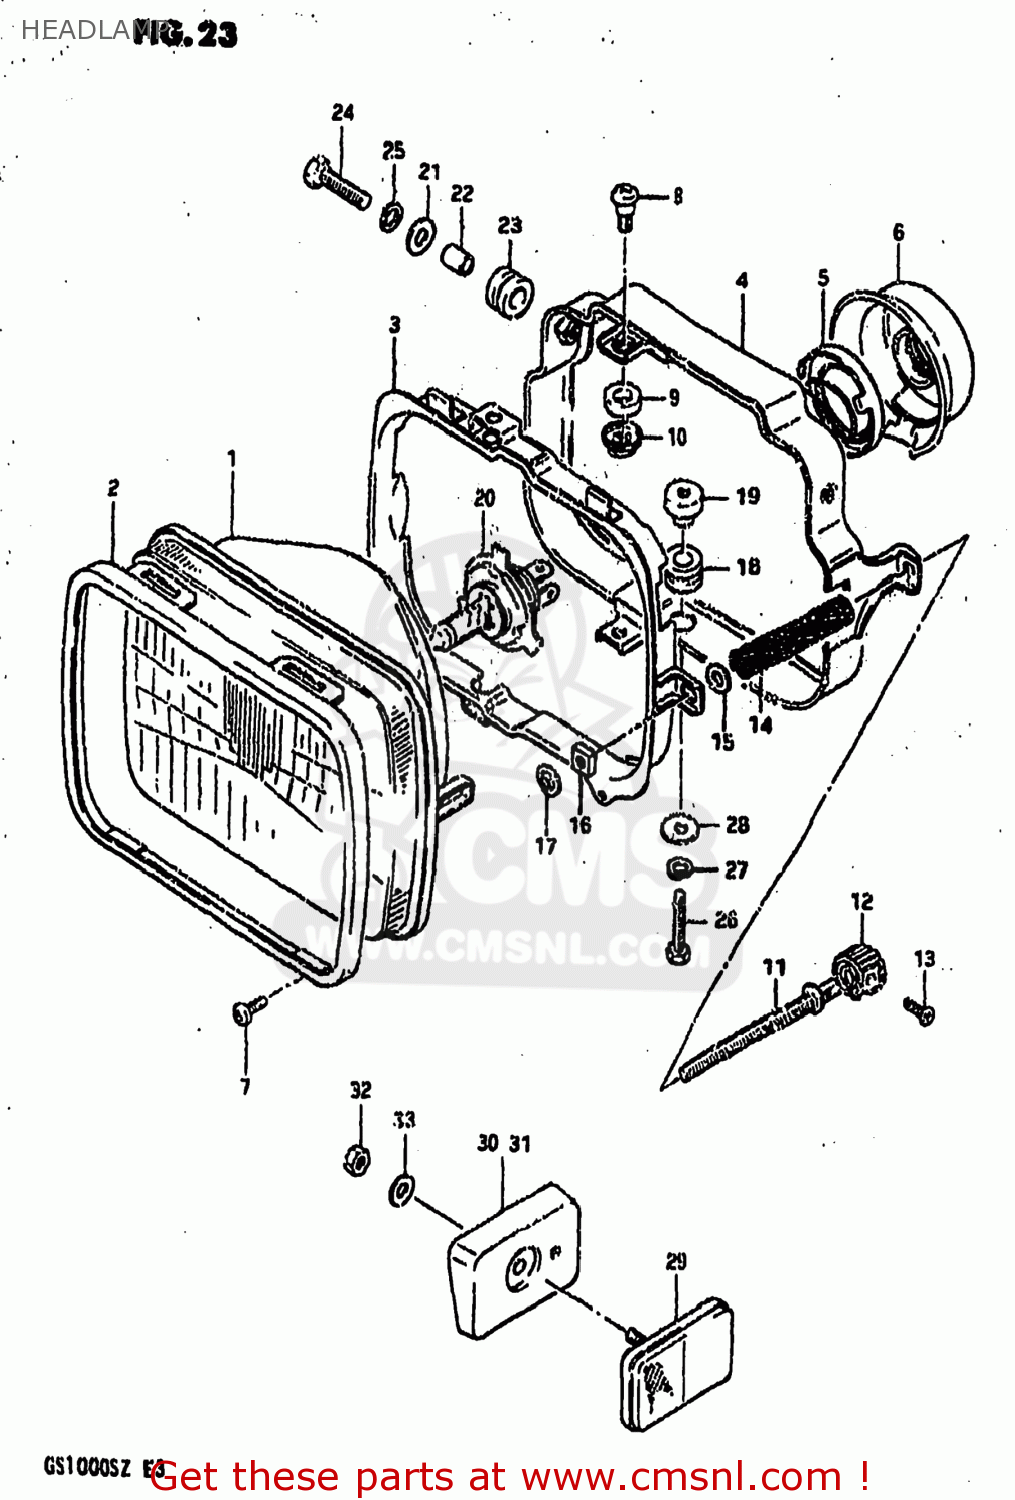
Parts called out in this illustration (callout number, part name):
1	LAMP UNIT
2	RETAINER
3	RING,MOUNTING
4	HOUSING
5	HOLDER, BULB
6	COVER,HEADLAMP SOCKET
7	SCREW
8	SCREW
9	SPACER
10	NUT,ADJUSTING
11	SCREW,ADJUSTING
12	KNOB,ADJUSTER
13	SCREW
14	SPRING
15	WASHER
16	NUT
17	NUT,HEADLAMP ADJUSTER
18	CUSHION
19	NUT
20	BULB(12V60/55W,H4)
21	WASHER
22	SPACER (6.1X8X9.5)
23	CUSHION
24	BOLT
25	LOCK WASHER
26	SCREW(6X20)
27	LOCK WASHER
28	WASHER
29	REFLECTOR,REFLEX
30	SPACER,FRONT REFLEX REFLECTOR
31	SPACER,FRONT REFLEX REFLECTOR
32	NUT
33	WASHER
